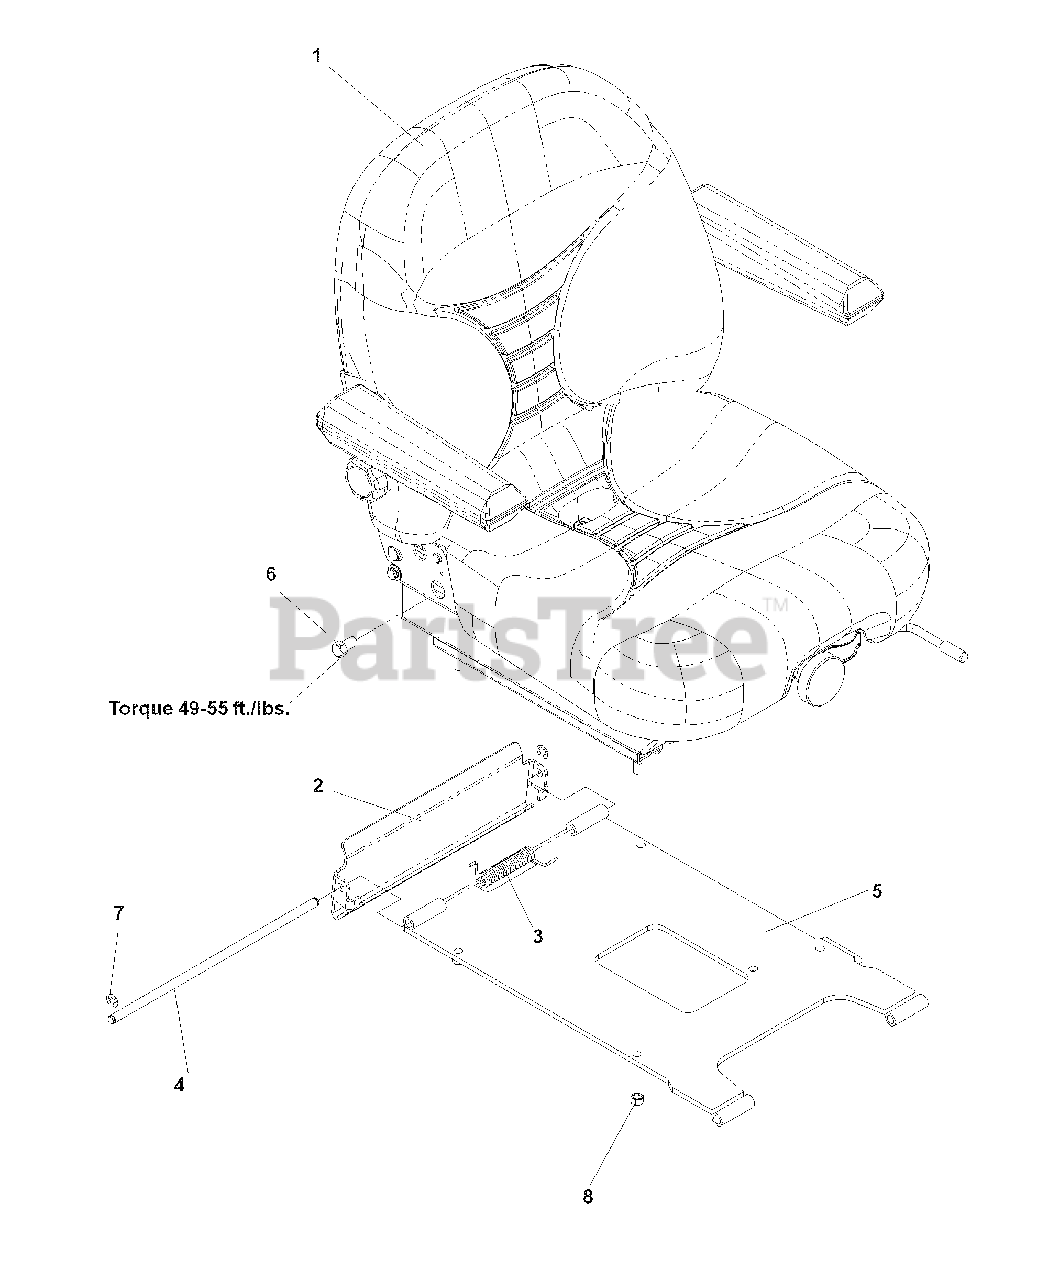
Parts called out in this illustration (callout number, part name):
1	SEAT, SUSPENSION
2	SEAT LATCH BRACKET
3	TORSION SPRING
4	SEAT LATCH ROD
5	SEAT MOUNT
6	HCS, 7/16-20 x 3/4
7	RING-RETAINING
8	NUT, 5/16-18, NYLOC
